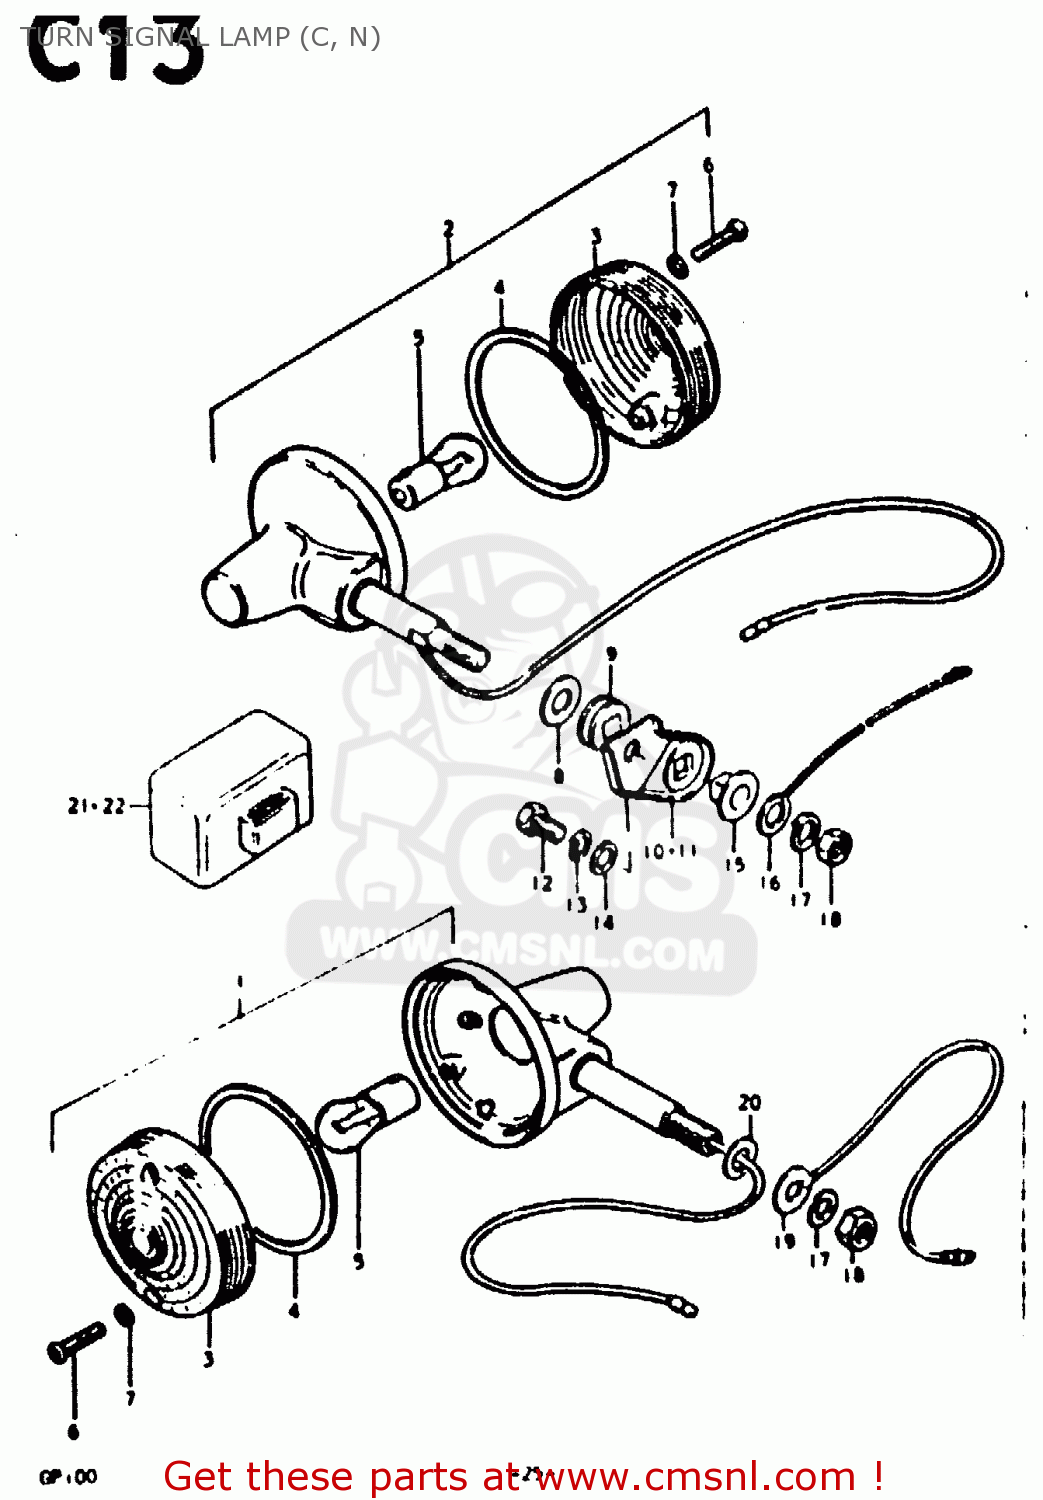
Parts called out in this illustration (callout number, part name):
1	LAMP ASSY, FRONT TURN SIGNAL
2	LAMP ASSY, REAR TURN SIGNAL
3	LENS
4	GASKET (NAS)
5	BULB(6V8W,STANLEY,A4115)
6	SCREW
7	GASKET (NAS)
17	LOCK WASHER
18	NUT
19	LEAD WIRE,EARTH
20	WASHER
21	RELAY, TURN SIGNAL
